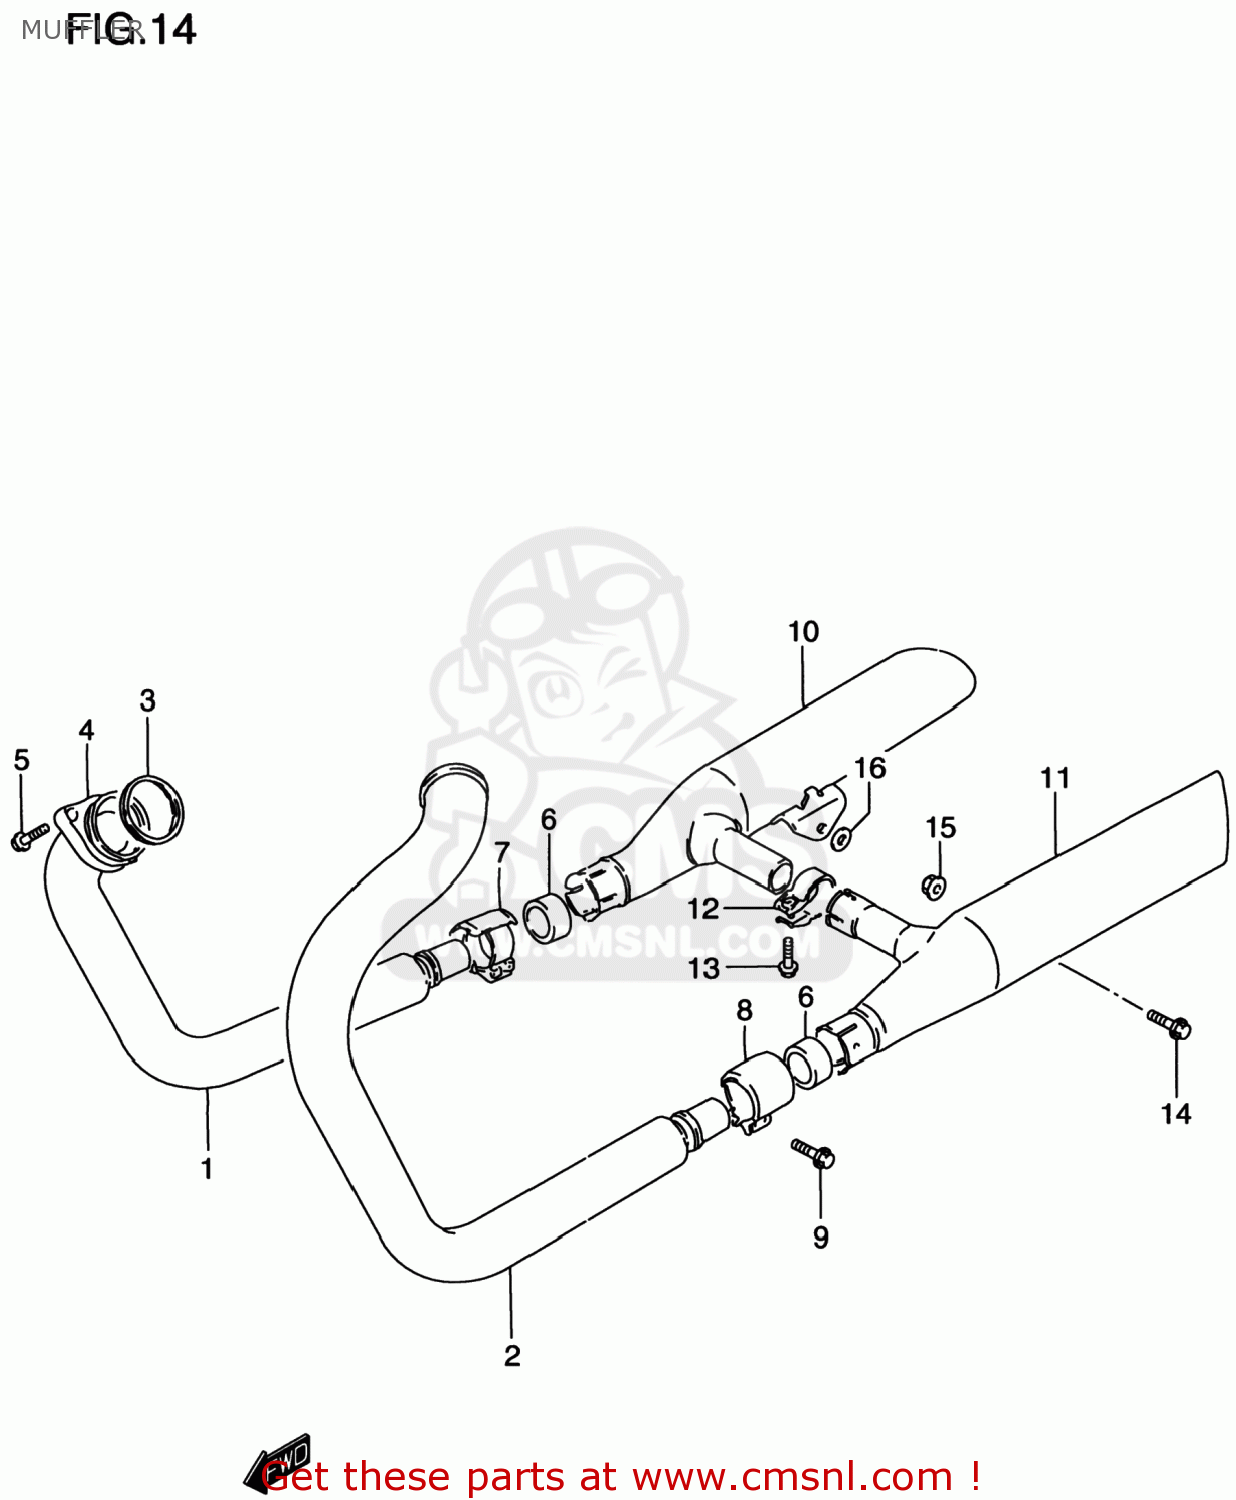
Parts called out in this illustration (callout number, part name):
1	PIPE,EXHAUST,R
2	PIPE,EXHAUST,L
3	GASKET,EXHAUST PIPE (NAS)
4	CLAMP,EXHAUST PIPE
5	BOLT(8X35)
6	CONNECTOR,EXHAUST PIPE
7	CLAMP,MUFFLER CONNECTOR,R
8	CLAMP,MUFFLER CONNECTOR,L
9	BOLT,G/S SWITC
10	BODY,MUFFLER,R
11	BODY,MUFFLER,L
12	CLAMP,EXHAUST COUPLER
13	BOLT
14	BOLT
15	NUT
16	WASHER(8.5X18X3.20)
